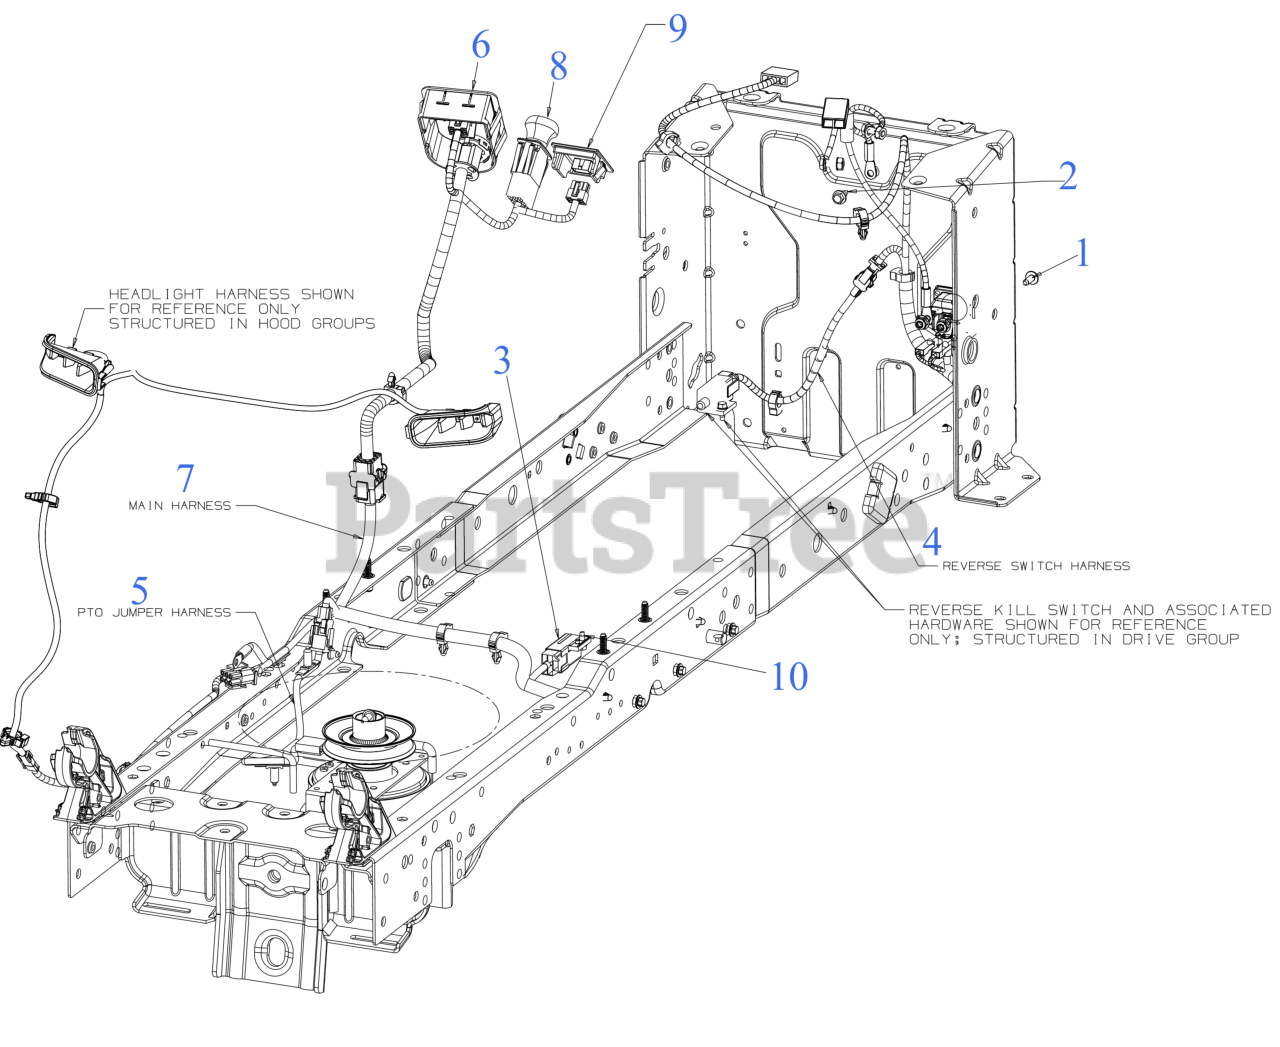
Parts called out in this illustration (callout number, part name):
1	SCREW M6-1 x .625
2	SCREW 1/4-20X.625
3	INTERLOCK SWITCH (NO/NC)
4	REVERSE HARNESS
5	CLUTCH HARNESS 11"
6	IGNITION MODULE SWITCH (RMC ELC PTO WHTE)
7	HARNESS (EPTO/RMC/HRMTR/DC)
7	12V SOLENOID
8	PTO SWITCH (YELLOW KNOB)
9	DASH HOUR METER PLUG
10	SHOULDER SCREW
